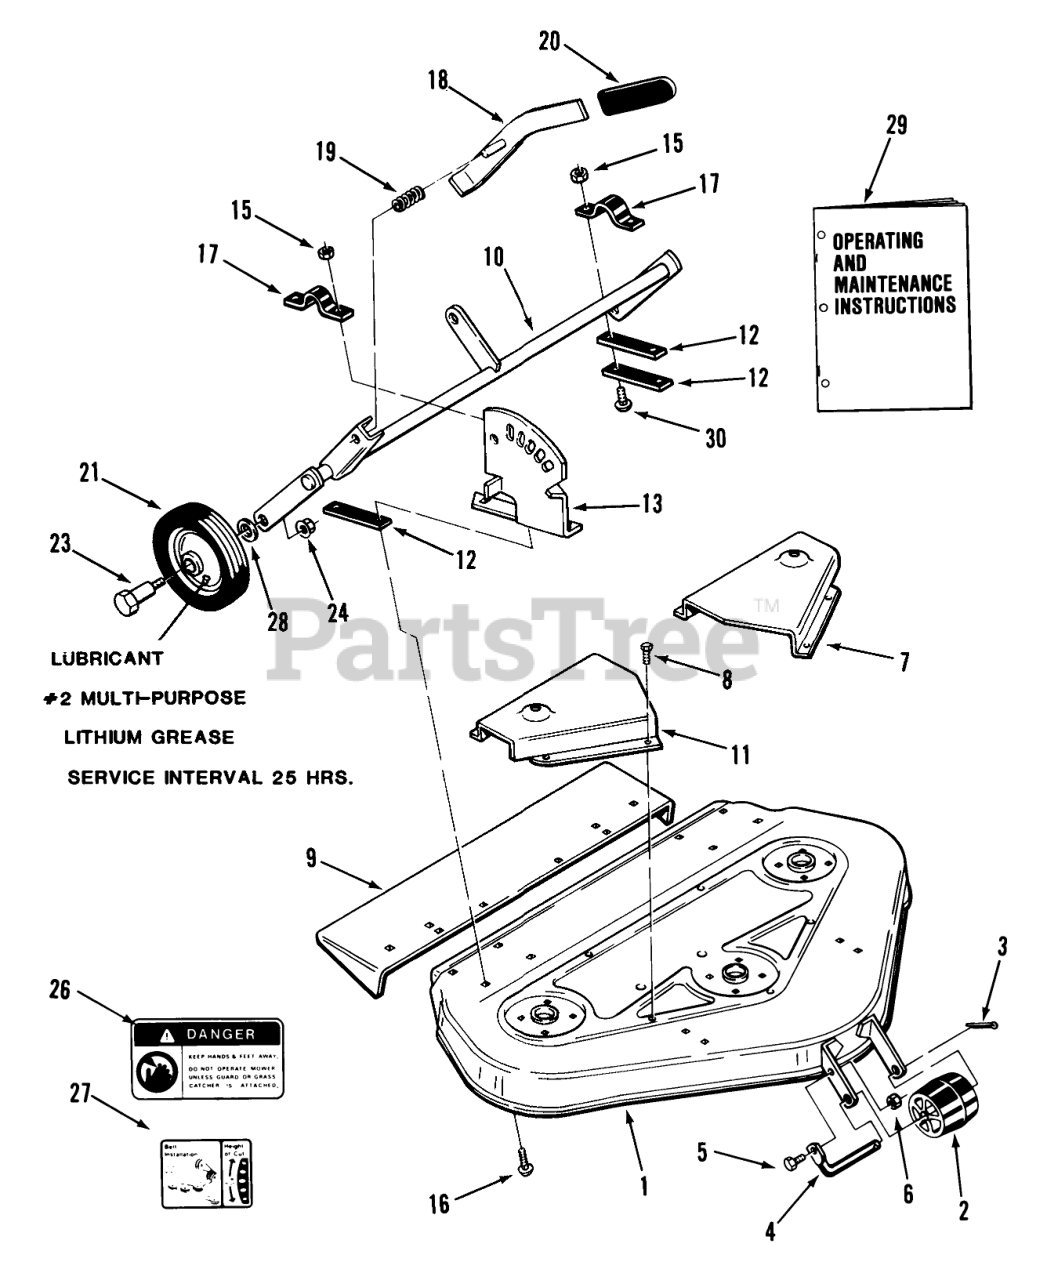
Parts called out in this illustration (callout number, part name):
1	Mower Deck
2	Roller
3	Cotter Pin
4	ROLLER-SHAFT
5	H H C S
6	Nut
7	Cover-Belt
8	SCREW -4
9	Chute Extension
10	Gage Wheel Support
11	Belt Cover RH
12	Bar
13	Quadrant
15	Nut
16	Bolt
18	Lever
19	SPRING-COMPRESSION
21	WHEEL
23	BOLT-SHOULDER
24	Nut
26	Danger Decal
27	DECAL-HEIGHT & BELT
28	WASHER
29	Operating and Maintenance Instructions
30	Bolt
